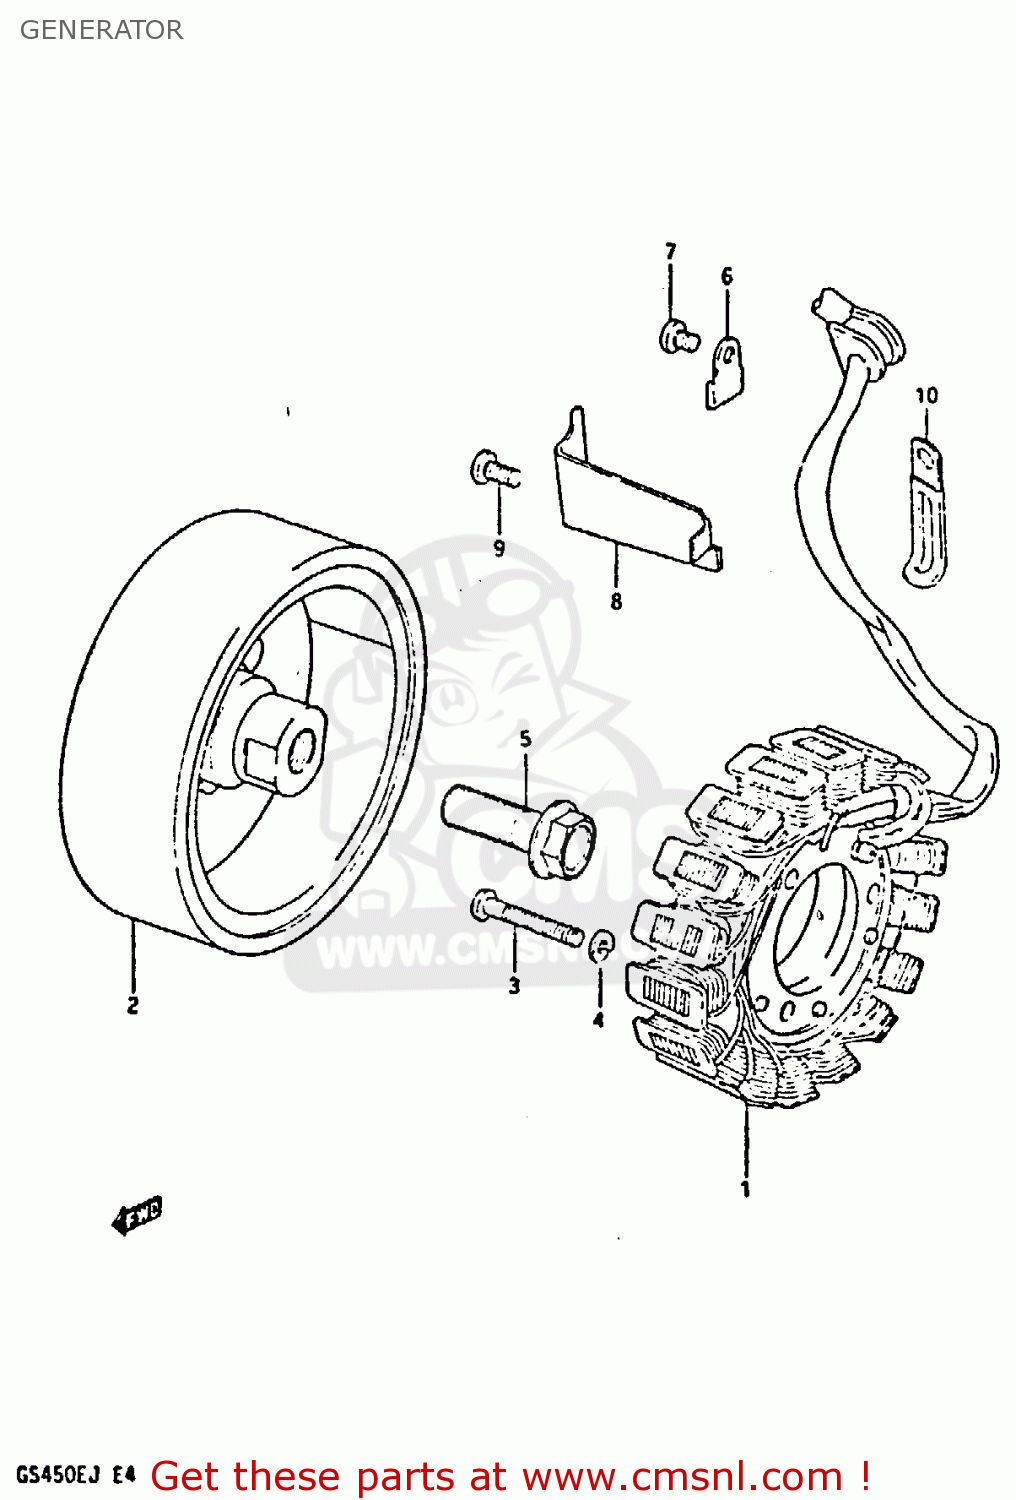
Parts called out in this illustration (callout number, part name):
1	STARTER ASSY
2	ROTOR ASSEMBLY
3	SCREW
4	LOCK WASHER
5	BOLT(12X40)
6	CLAMP,GENERATOR LEAD WIRE
7	SCREW
8	CLAMP,GENERATOR LEAD WIRE
9	SCREW
10	CLAMP L:35
